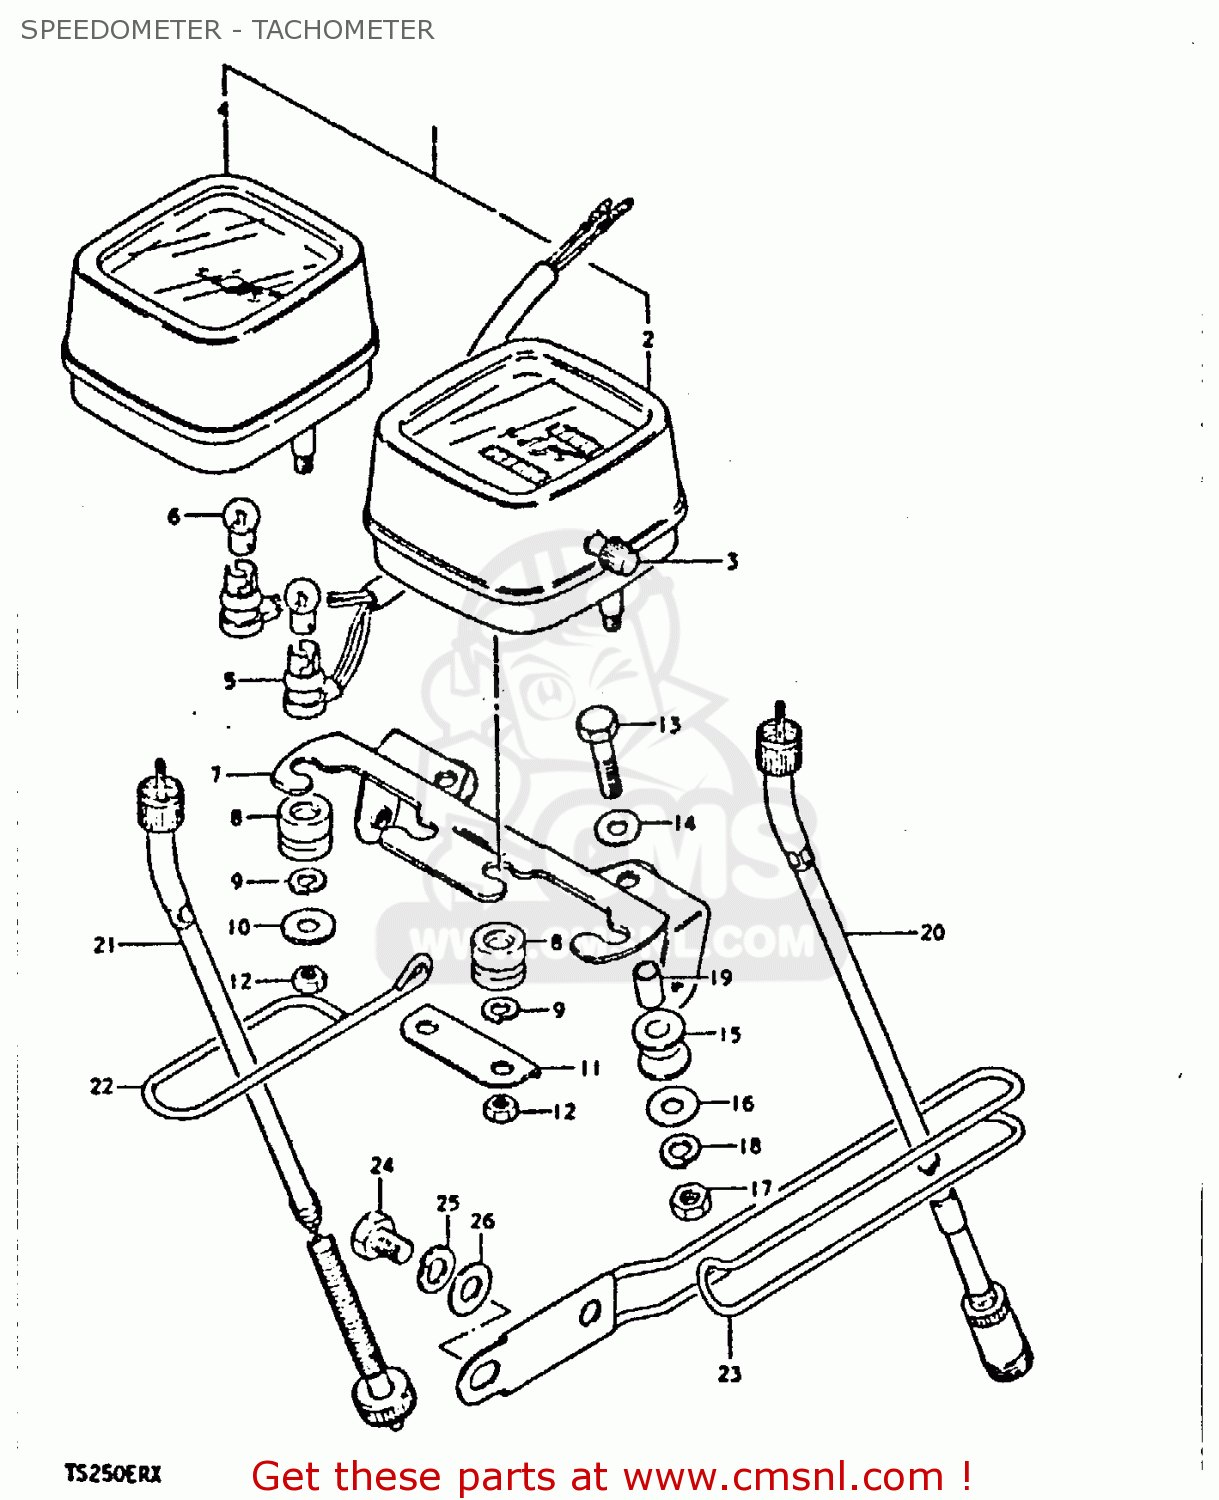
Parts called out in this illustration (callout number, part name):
1	SPEED/TACHOMETER ASSY
2	METER,SPEEDOMETER (KM/MPH)
3	KNOB,TRIP METER
4	TACHOMETER
5	SOCKET,METER
6	BULB(6V/3W)
7	BRACKET,COMBINATION METER
8	CUSHION
9	LOCK WASHER
10	WASHER,METER
11	PLATE,METER CONNECTING
12	NUT
13	BOLT
14	WASHER
15	CUSHION
16	WASHER
17	NUT
18	LOCK WASHER
19	SPACER (6.1X8X15.5)
20	CABLE ASSEMBLY,SPEEDOMETER
21	CABLE ASSEMBLY,TACHOMETER
22	GUIDE,TACHOMETER CABLE
23	GUIDE,CABLE
24	BOLT 8X12
25	LOCK WASHER
26	WASHER
